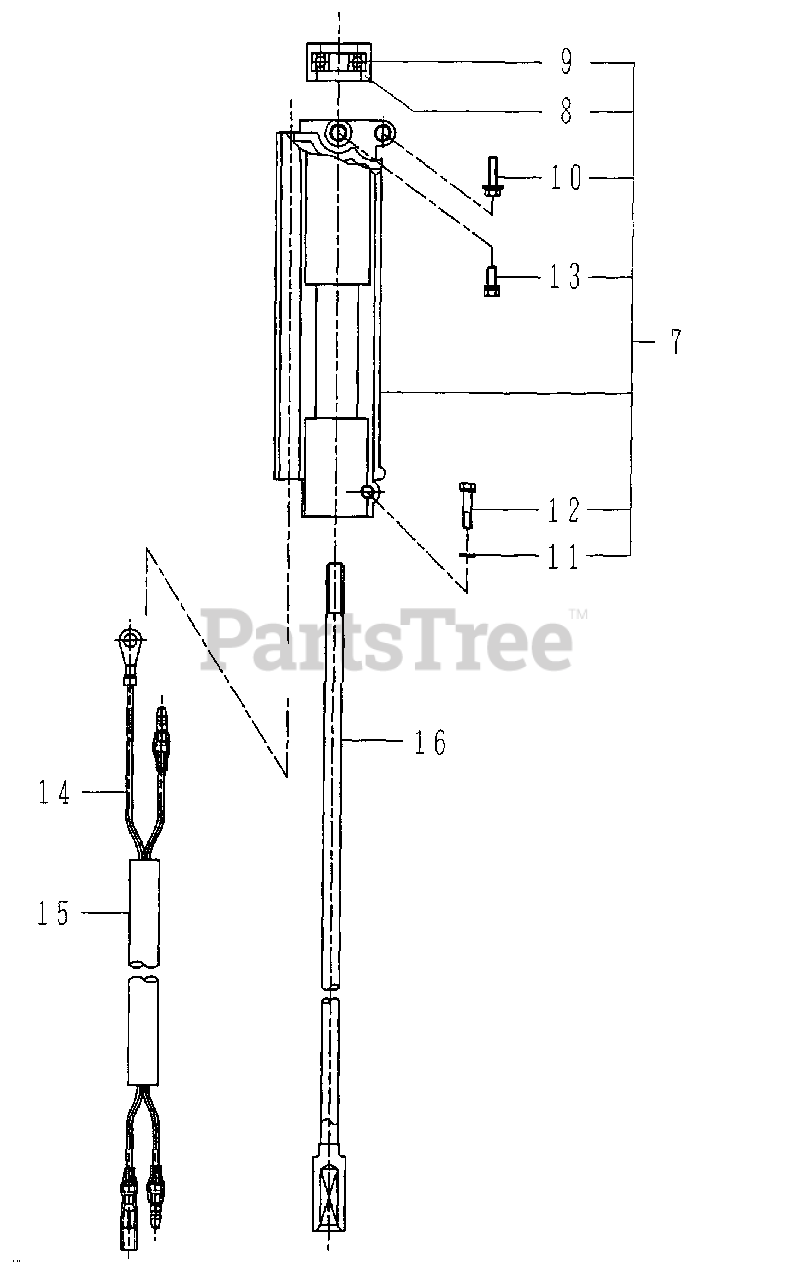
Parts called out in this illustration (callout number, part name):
7	CONNECTOR
8	COVER, BEARING
9	BEARING, BALL
10	BOLT
11	LOCKWASHER
12	BOLT
13	BOLT
14	LEAD - GROUND
15	TUBE, PROTECTIVE
16	PIPE, MAIN
